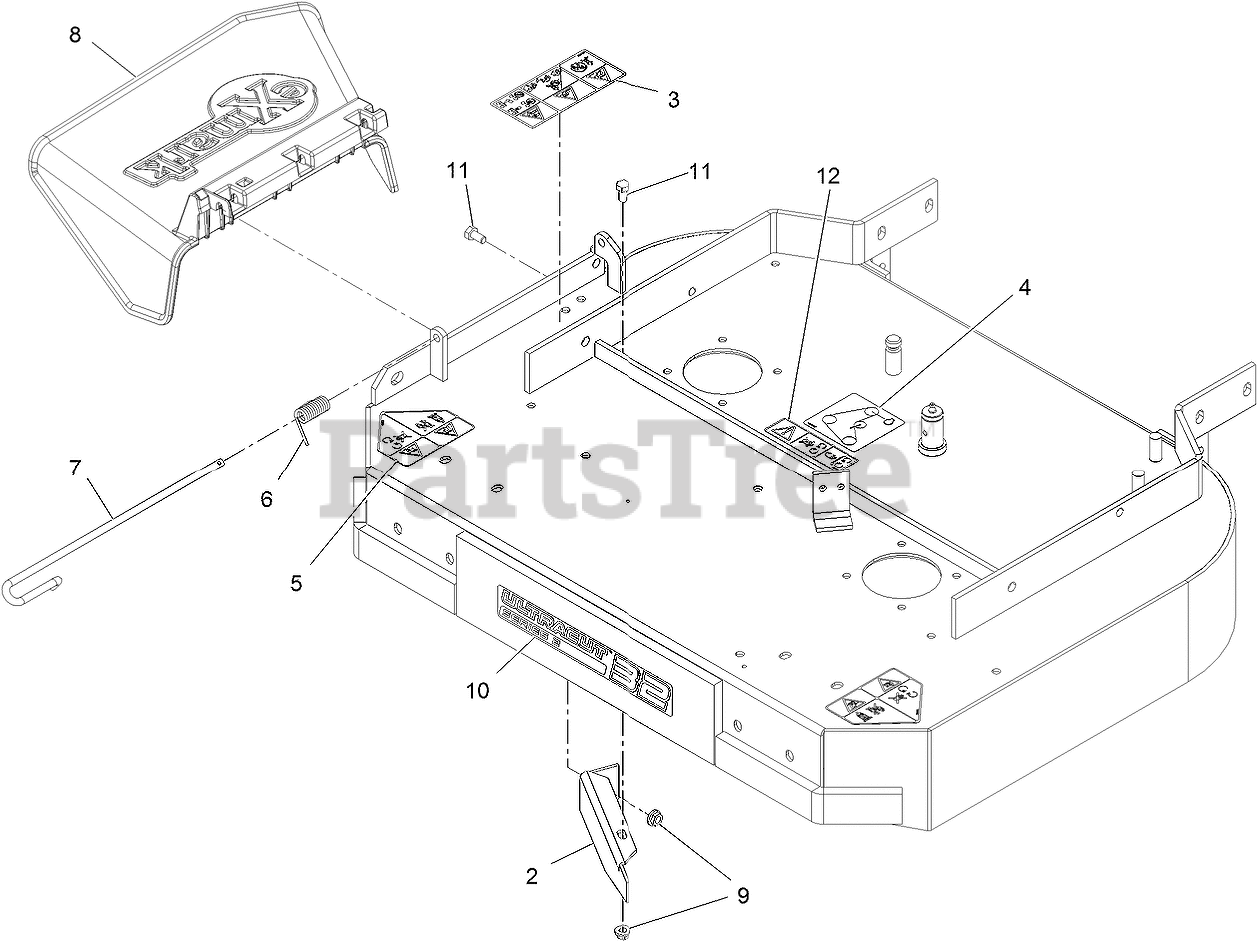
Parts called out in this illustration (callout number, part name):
2	BAFFLE-DOGLEG
3	DECAL-WARNING THROWN OBJ
4	DECAL-BELT ROUTING 32-36
5	DECAL-DANGER
6	SPRING, TORSION
7	PIN-CHUTE
8	CHUTE DEFLECTOR XRK M056
10	DECAL-ULTRACUT 32 SERIES 2
11	SCREW-HH
12	DECAL-COVER, MISSING
